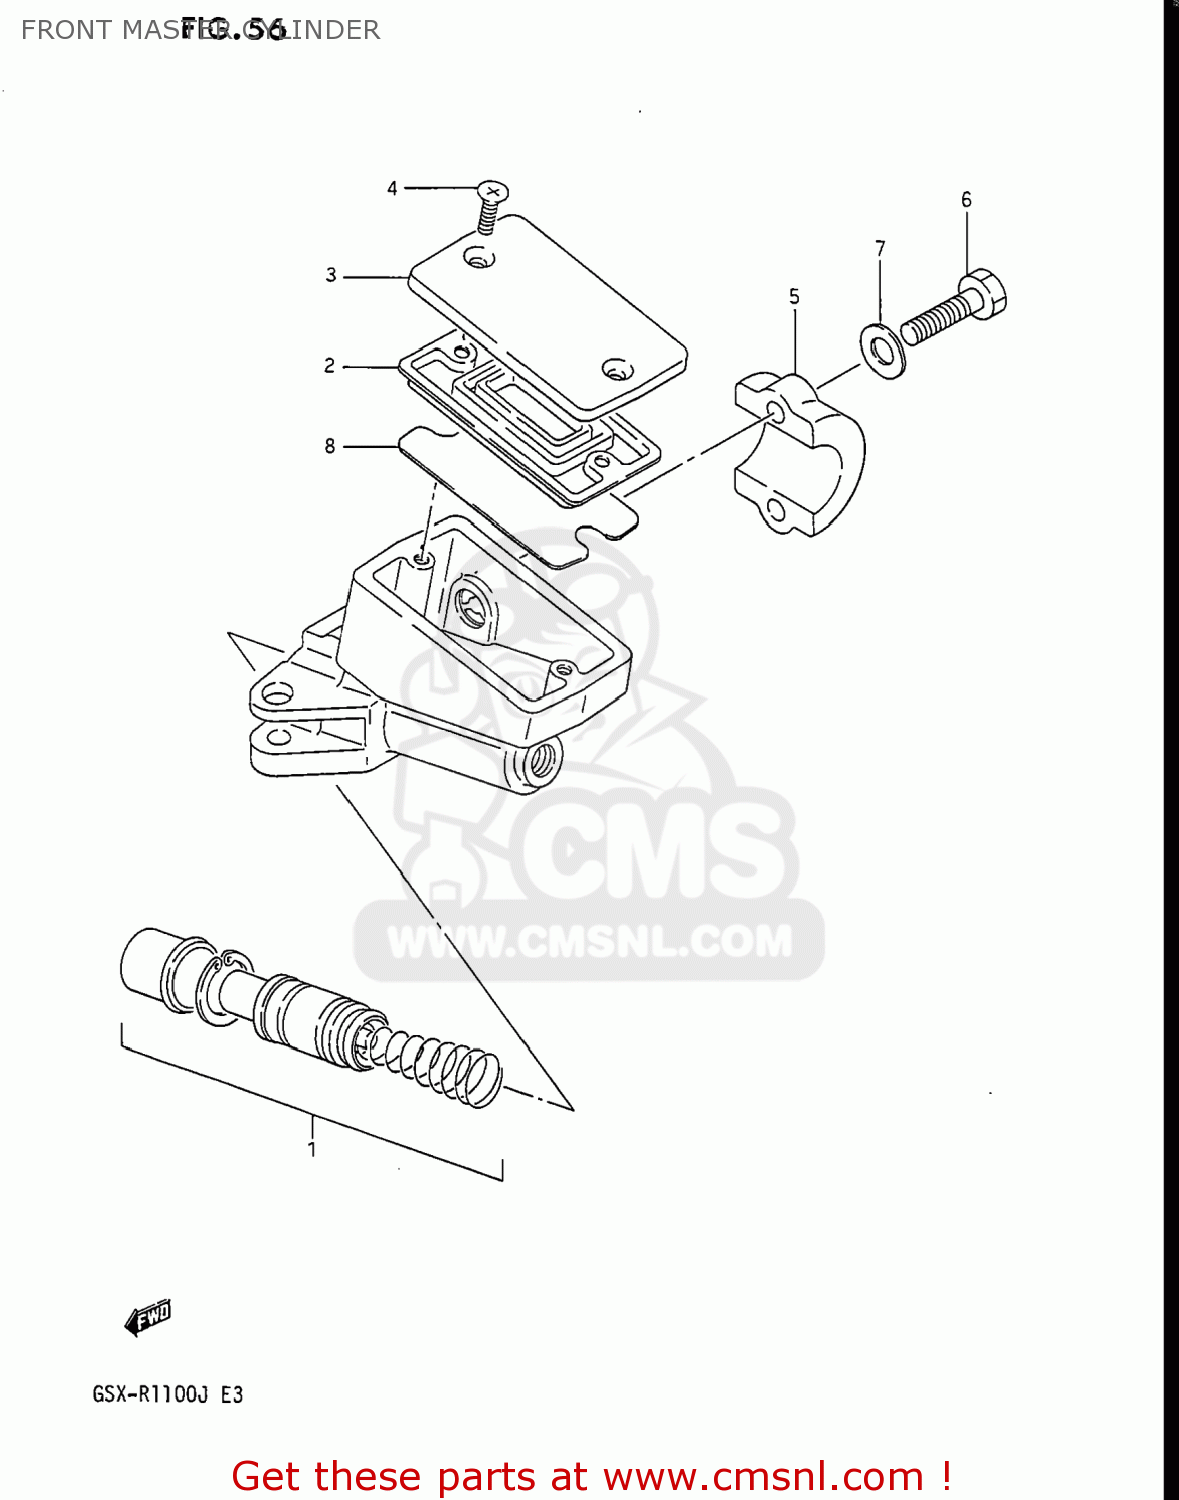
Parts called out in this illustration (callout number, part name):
1	PISTON & CUP SET
2	3
3	CAP
4	SCREW
5	HOLDER,MASTER CYLINDER
6	BOLT
7	WASHER
8	FLOAT
